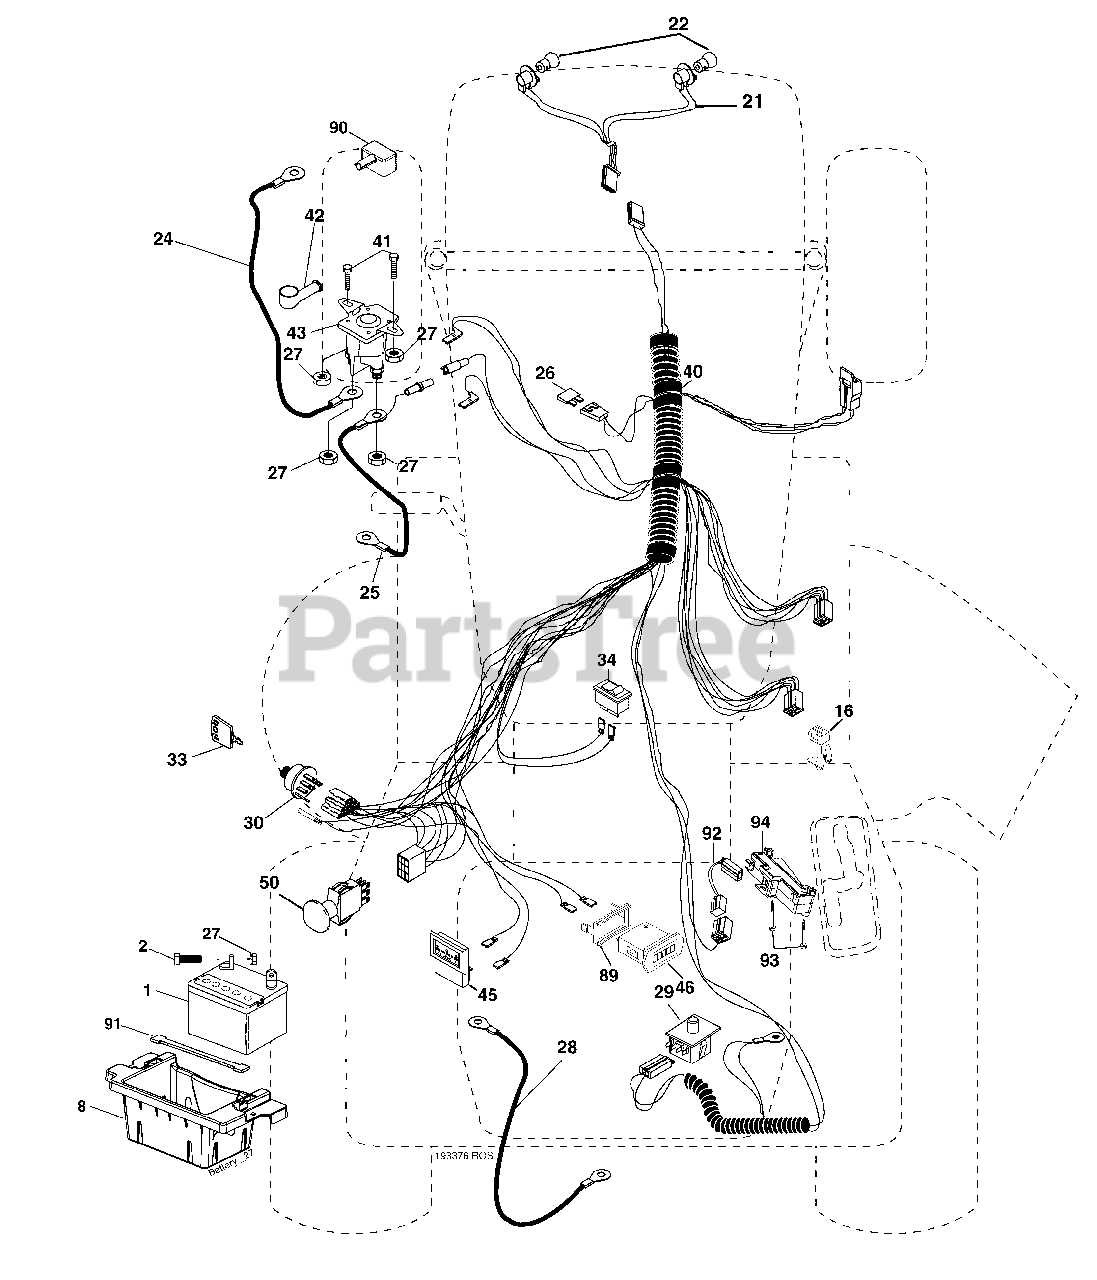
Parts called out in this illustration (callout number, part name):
1	Battery
2	Bolt Hex Hd 1/4-20 unc x 3/4
8	Box Battery
16	Switch Interlock Push-In
21	Harness Asm Light W/4152j
22	Bulb Light #1156
24	Cable Battery 6 Ga. 11" red
25	Cable Battery 6 Ga. 22" red w/16 wire
26	Fuse 20 AMP
27	Nut Keps Hex 1/4-20 unc
28	Cable Ground black
29	Switch Seat DP w/ROS
30	Switch Ign
33	Key Ign Molded Generic
34	Switch Light/Reset
40	Harness Ign.
41	Bolt 1/4-20 x 1/2
42	Cover Terminal Red
43	Solenoid
46	Hourmeter Snap-In
50	Switch PTO
89	Bracket Snap-In Hourmeter
90	Cover Terminal
91	Strap Battery
92	Harness Pigtail Revers Switch
93	Screw Plastic 10-14 x 2.0
94	Module Reverse ROS
